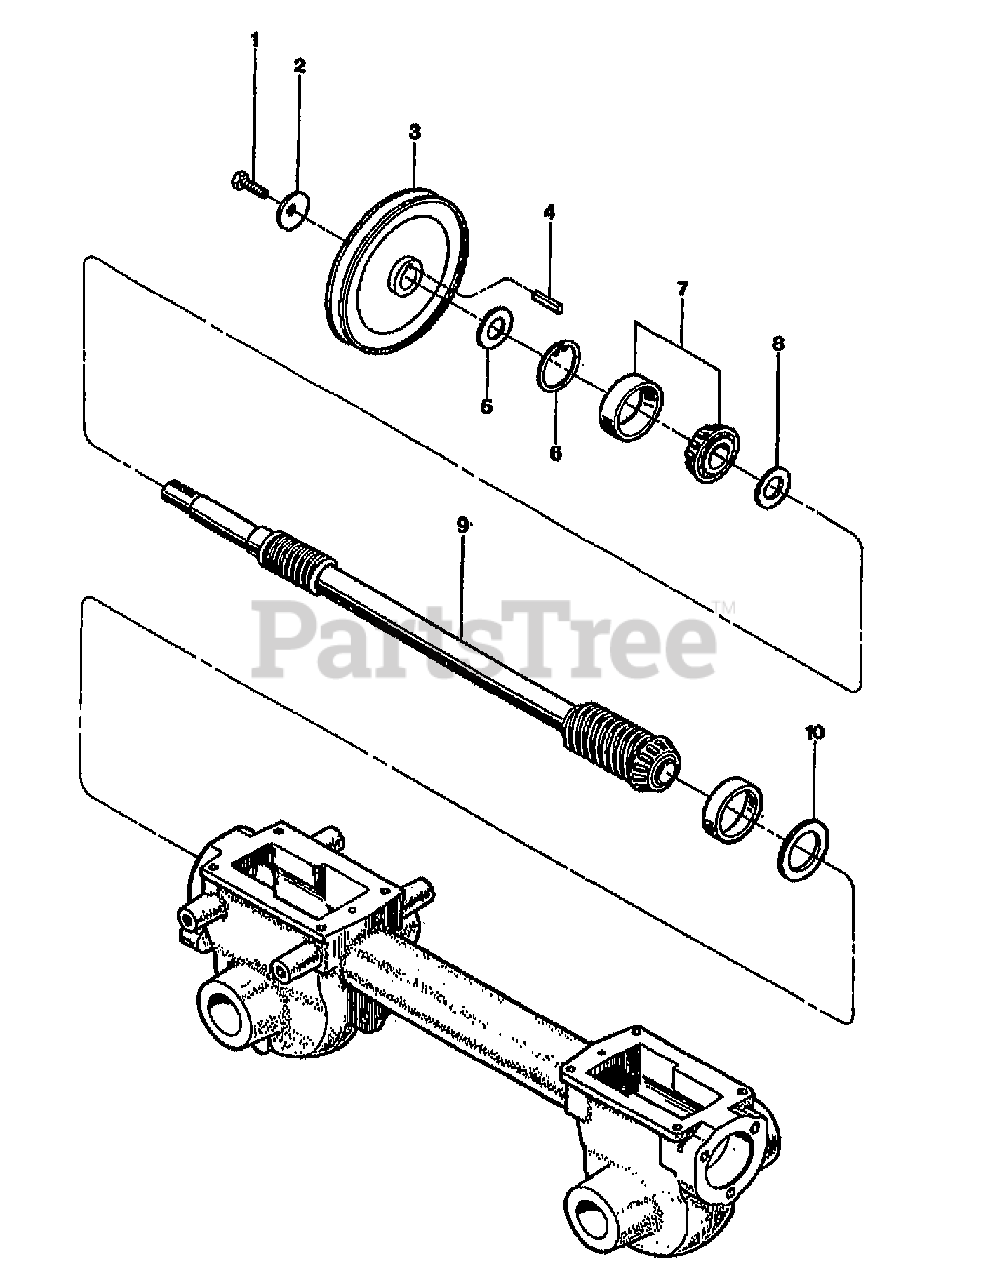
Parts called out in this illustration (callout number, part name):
1	SCR-HH 5/16-24X.75 G5 ZP
2	WASHER-.827X.331X.098
3	PULLEY-TRANSMISSION
4	KEY-.188 SQX1.0
5	WASHER-SHLDR HARDENED
6	RING-RETAINING 5000-181
7	KIT-BRG CONE&RACE-DRIVESHAFT
8	WASHER-#1.25X.75X.06
9	DRIVESHAFT-MACH
10	SHIM-1.75X1.5X.01
10	SHIM-1.75X1.5X.03
10	SHIM-1.75X1.5X.005
10	SHIM-1.75X1.5X.062
10	SHIM SET-DRIVESHAFT-HORSE (INCL. 2 #1224-1, 2 #1224-2, 1 #1224-3, 1 #1224-4)
